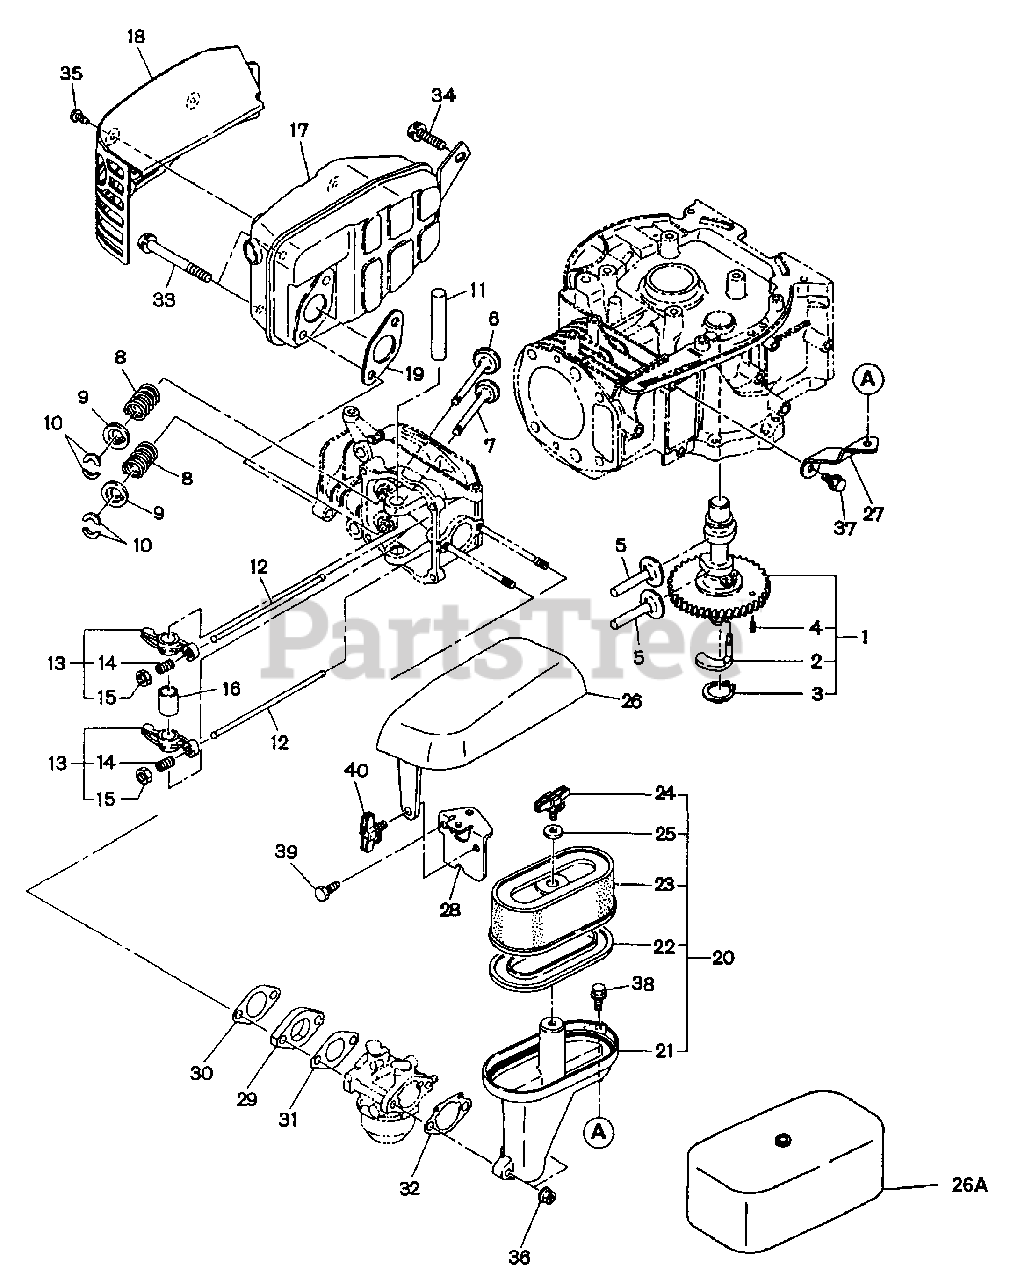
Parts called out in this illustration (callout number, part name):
1	CAMSHAFT, compl.
2	RELEASE LEVER
6	INTAKE VALVE
7	EXHAUST VALVE
8	VALVE SPRING
11	ROCKER SHAFT
12	PUSH ROD, compl.
13	ROCKER ARM ASS'Y
14	ADJUSTING SCREW
17	MUFFLER, compl.
18	MUFFLER COVER, compl., yellow zinc
18	MUFFLER COVER, compl., black
19	GASKET, exhaust., compl.
20	AIR CLEANER ASSY
21	CASE, Air Cleaner
23	ELEMENT SET
26	AIR CLEANER COVER (Pro Poly)
26A	AIR CLEANER COVER (Classic Steel)
27	BRACKET, air cleaner
28	BRACKET, air cleaner cover
30	GASKET, insulator
31	GASKET 2, insulator
32	GASKET, inner vent
33	BOLT and WASHER ASS'Y
34	BOLT and WASHER ASS'Y
35	TAPPING SCREW
37	FLANGE BOLT
38	FLANGE BOLT
39	TAPPING BOLT
40	WING BOLT (Pro Poly)
